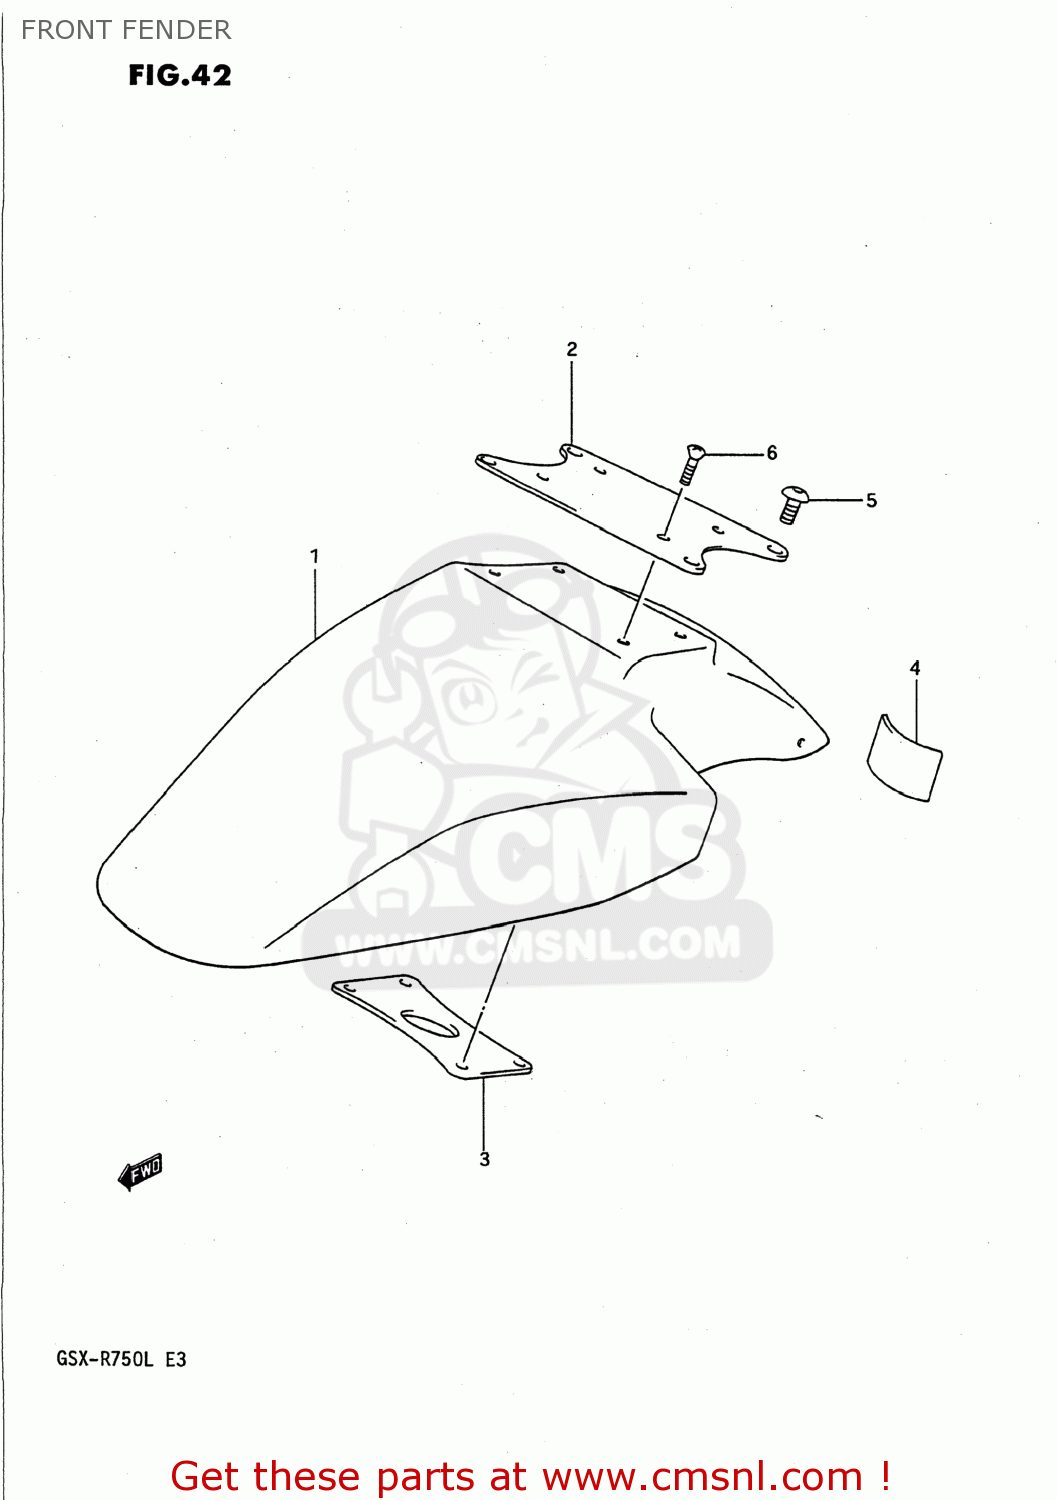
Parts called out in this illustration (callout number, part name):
1	FENDER,FRONT
2	BRACE,FR FENDER
3	BRACE,FR FENDER INNER
4	CUSHION,FR FENDER
5	SCREW(8X16)
6	SCREW(5X18)
